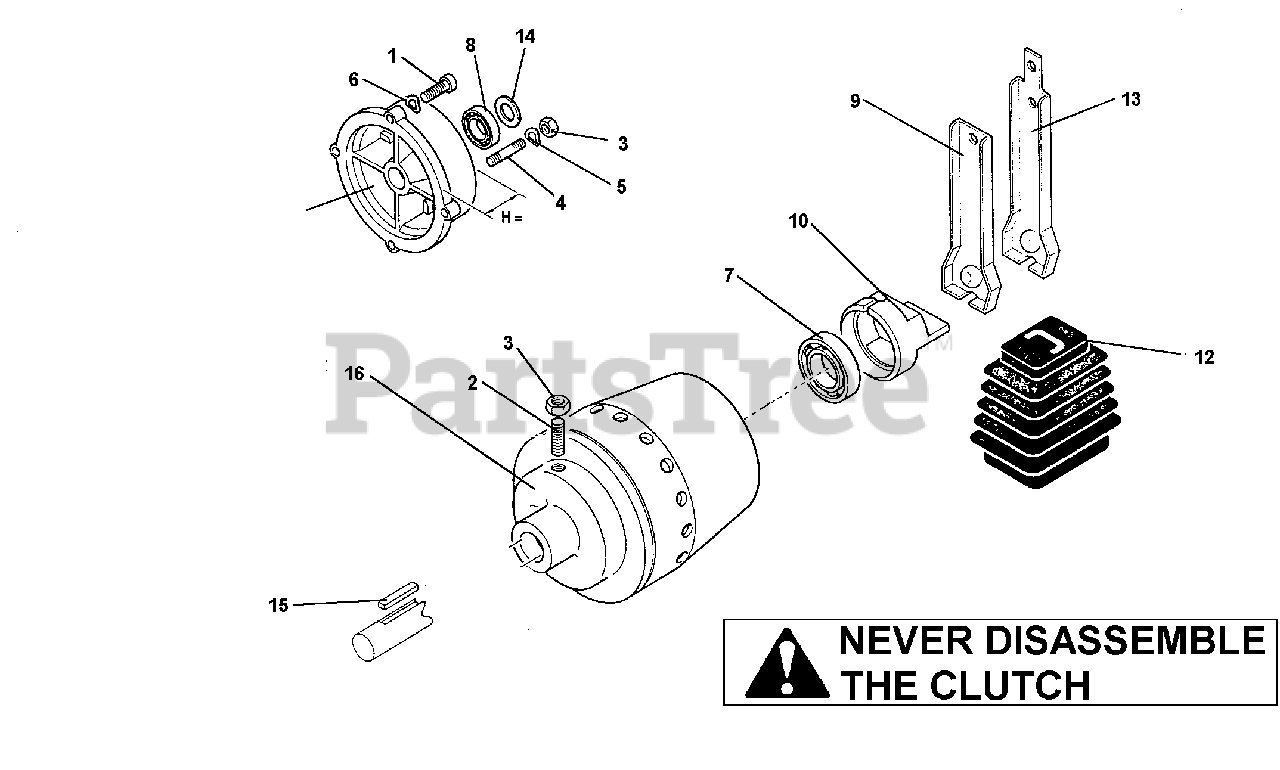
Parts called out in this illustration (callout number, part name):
1	SCREW 7/16 X 1 1/4"
2	SET SCREW M8X30
5	WASHER, WAVE
7	BEARING17X40X12
8	BEARING,30X55X13
9	CLUTCH LEVER, ELECTRIC START
10	CONE PUSHER
11	FLANGE, VANGARD
13	CLUTCH LEVER, RECOIL START
16	HEAVY DUTY CLUTCH, VANGARD
